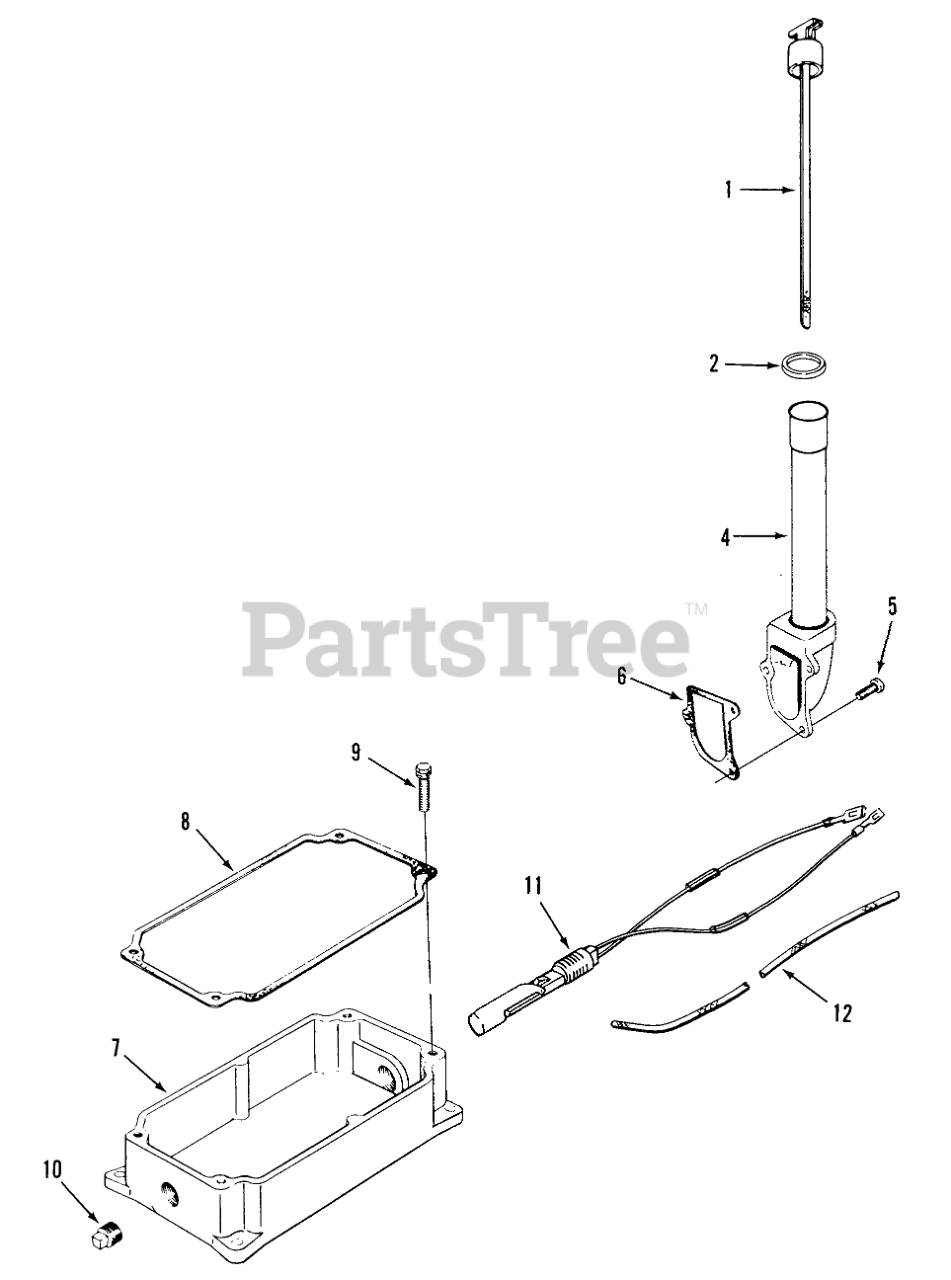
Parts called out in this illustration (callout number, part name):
1	Dipstick
4	Adapter-Oil Fill
5	Screw
6	Gasket
7	Oil Pan
8	Gasket
9	Screw
10	Plug
11	Float Switch Kit (Includes Items 12 & Decal)
12	Sleeving
